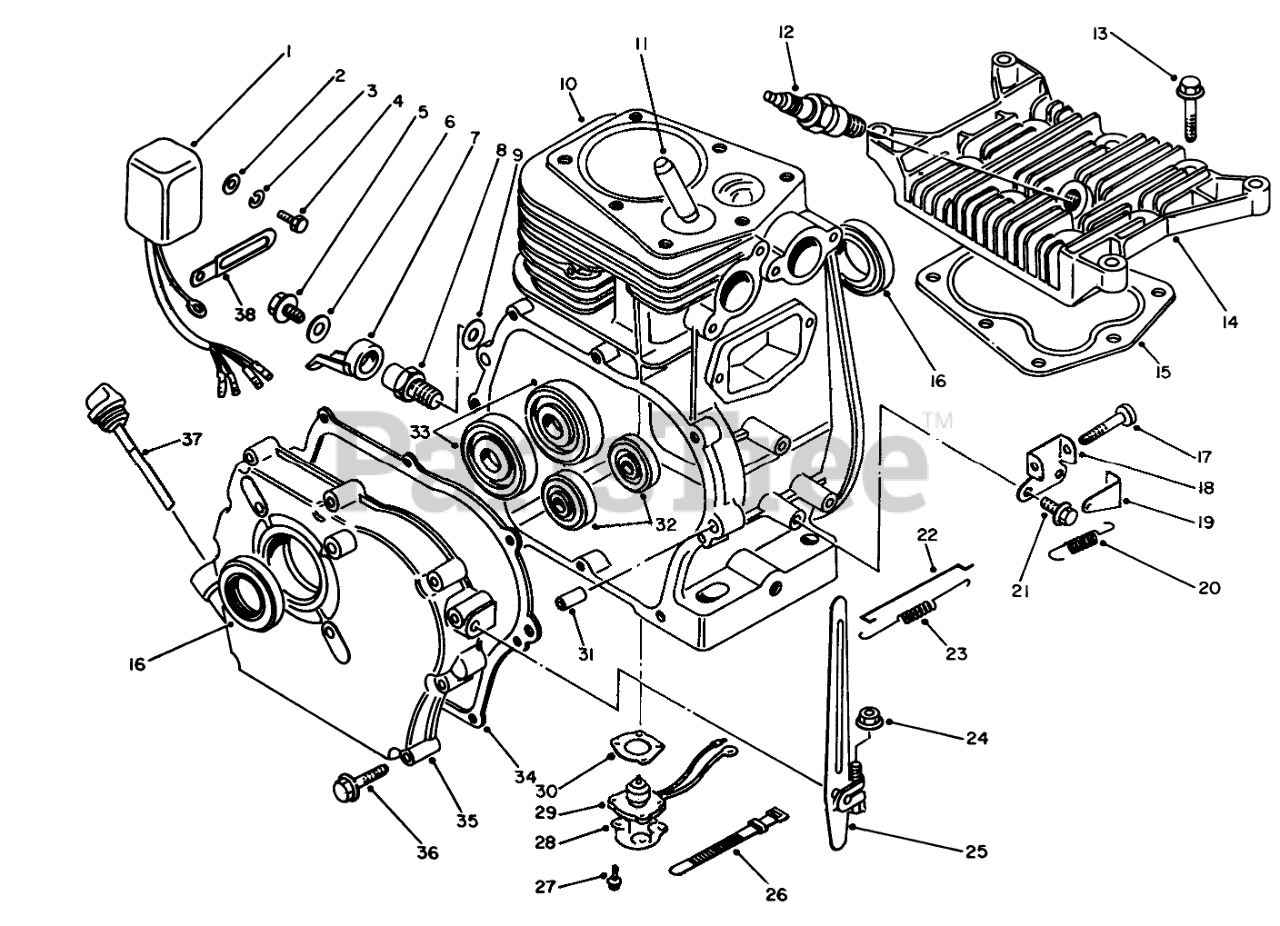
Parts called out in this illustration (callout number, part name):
1	OIL LEVEL UNIT
2	Washer
3	Lockwasher
5	Bolt
6	Gasket
7	Plate
8	Adapter
9	GASKET
10	Cylinder
11	VALVE GUIDE
12	SPARK PLUG
14	Cylinder Head
15	GASKET
16	OIL SEAL
18	Bracket
20	SPRING
22	Rod
23	SPRING
24	M6 X 1 LOCKNUT
25	Control Lever
26	Clamp
28	Plate
29	Sensor
30	GASKET
32	Bearing
33	Screw
34	Gasket
35	Cover
37	Gasket
38	Clamp
